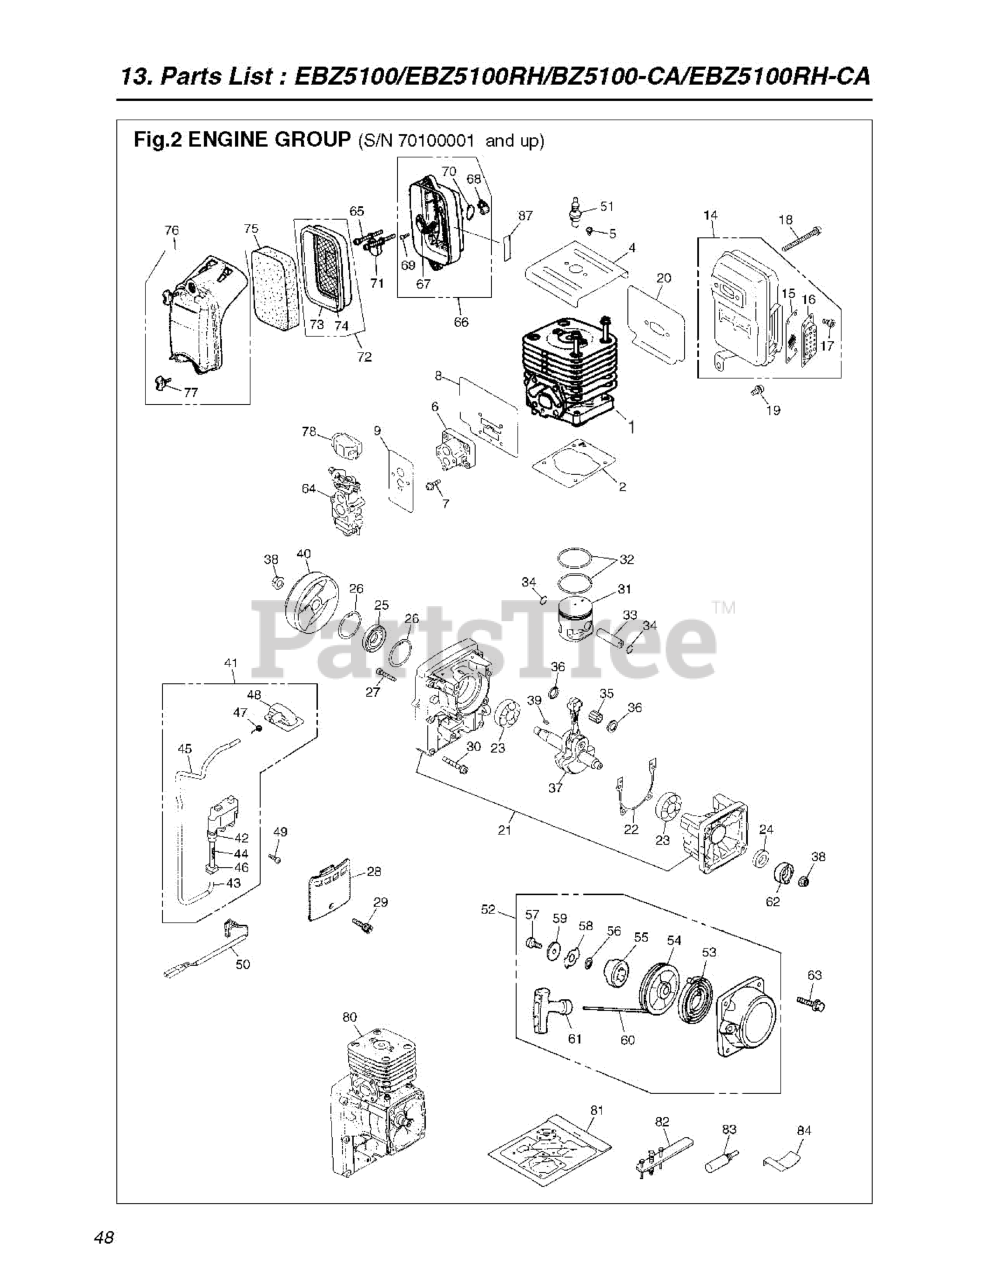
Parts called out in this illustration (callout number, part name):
1	CYLINDER
2	GASKET, BASE
3	BOLT
4	PLATE, CYLINDER
5	SCREW TORX
6	INSULATOR
7	BOLT
8	GASKET, INSU
9	GASKET, CARB
14	MUFFLER ASSY
15	ARRESTER
16	DIFFUSER
17	Bolt
18	BOLT
19	BOLT
20	GASKET, MUFFLER
21	CRANKCASE-C
22	GASKET, CASE
23	BEARING (REPLACES 2810-21240)
24	SEAL, OIL 15 X 25 X 7
25	SEAL (REPLACES 1400-21220)
26	RING, SNAP, M35 X 1.5
27	BOLT
28	COVER
29	BOLT TORX
30	BOLT TORX
31	PISTON
32	RING
33	PIN, PISTON
34	RING, SNAP
35	BEARING
36	WASHER (RPLS 1491-41510)
37	CRANKSHAFT COMP
38	NUT, M10
39	KEY
40	ROTOR
41	COIL ASSY
42	CAP
44	TUBE
45	TUBE
46	GROMMET
47	SPRING
48	CAP
49	BOLT TORX
50	CORD-C
51	SPARK PLUG
52	RECOIL ASSY
53	SPRING (RPLS -75220)
54	REEL
55	DOG
56	WASHER
57	SCREW
58	RETAINER (RPLS 1861-75161)
59	WASHER
60	ROPE
61	KNOB
62	PULLEY (RPLS -75210)
63	BOLT, TORX
64	CARBURETOR ASSY
65	BOLT
66	BODY-A
67	PLATE,CHOKE
68	LEVER
69	SCREW
70	RING,O
71	PLATE
72	PACKING-C
73	PACKING
75	ELEMENT
76	COVER ASSY
77	KNOB
78	COVER
80	SHORT BLOCK
81	GASKET KIT
82	PULLER ASSY
83	STOPPER (TOOL)
87	LABEL, CHOKE
